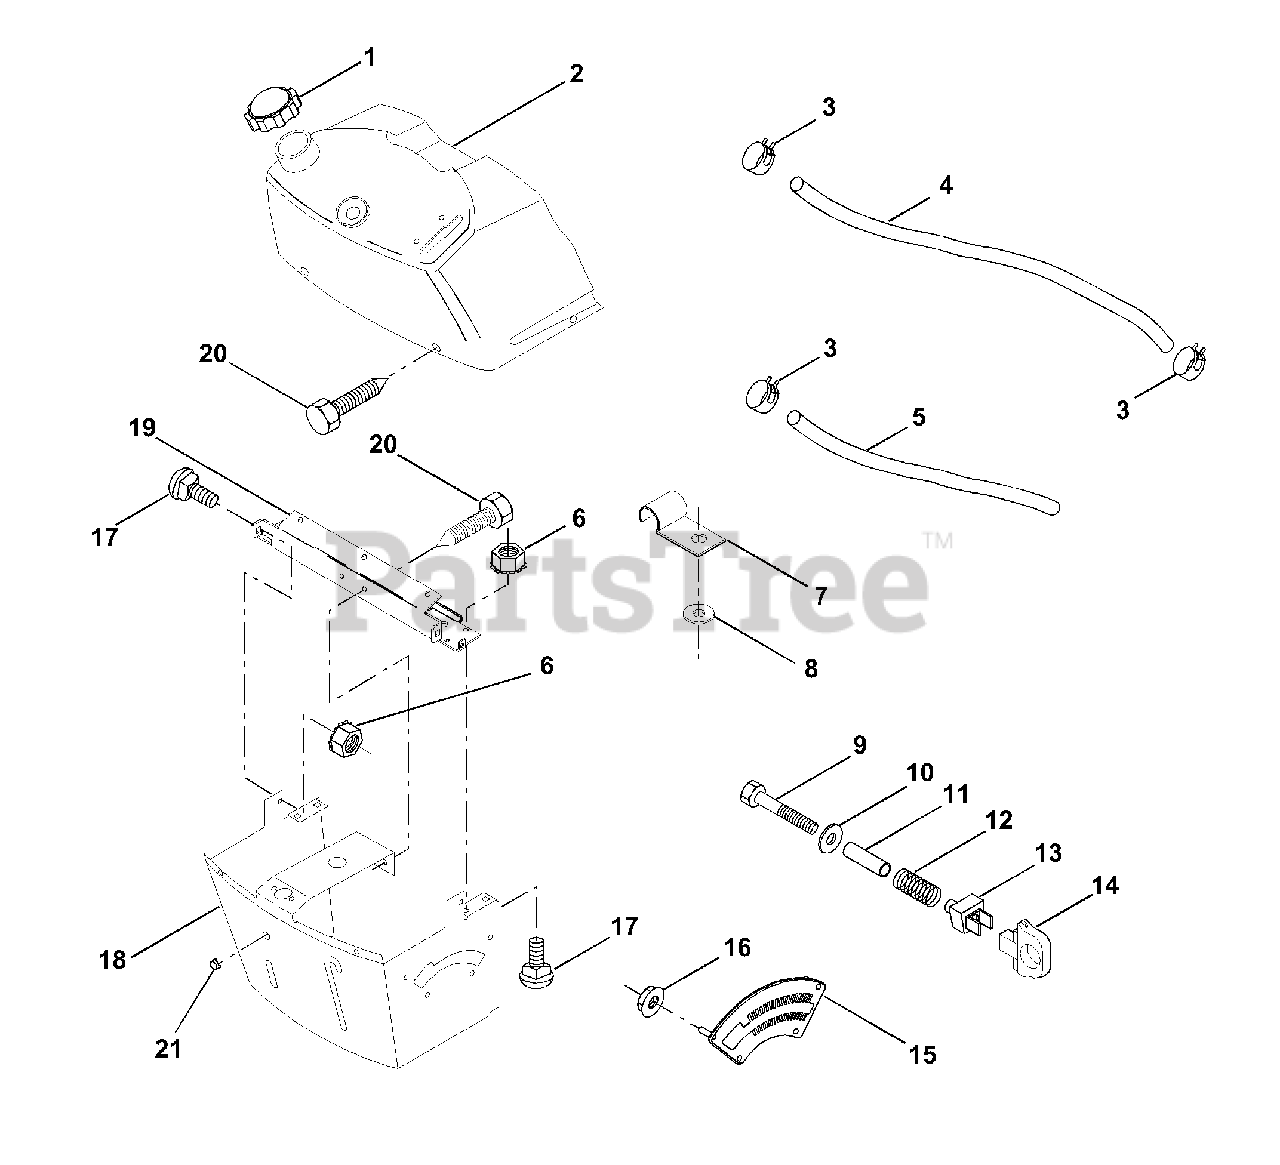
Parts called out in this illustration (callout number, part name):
2	Assembly, Dash & Fuel Tank
3	Clamp, Hose
4	Line, Fuel
5	Line, Fuel
6	Nut, Hex, Keps 1/4-20
7	Clip, Fuel Line
8	Washer 9/32 x 3/4 x 16 Ga.
9	Bolt, Hex, Fin 1/4-20 x 1-3/4
10	Washer 11/32 x 11/16 x 16 Ga.
11	Spacer, Split
13	Clip, Height Adjustment
14	Knob, Height Stop
15	Adjustment, Quadrant Height
16	Nut, Self-Threading 3/16-18
17	Bolt, Carriage 1/4-20 x 1/2 Gr. 5
18	Support Assembly, Dash
19	Brace, Cross
20	Screw, Self-Tapping 1/4-20 x 1/2
21	Plug Dome Black
